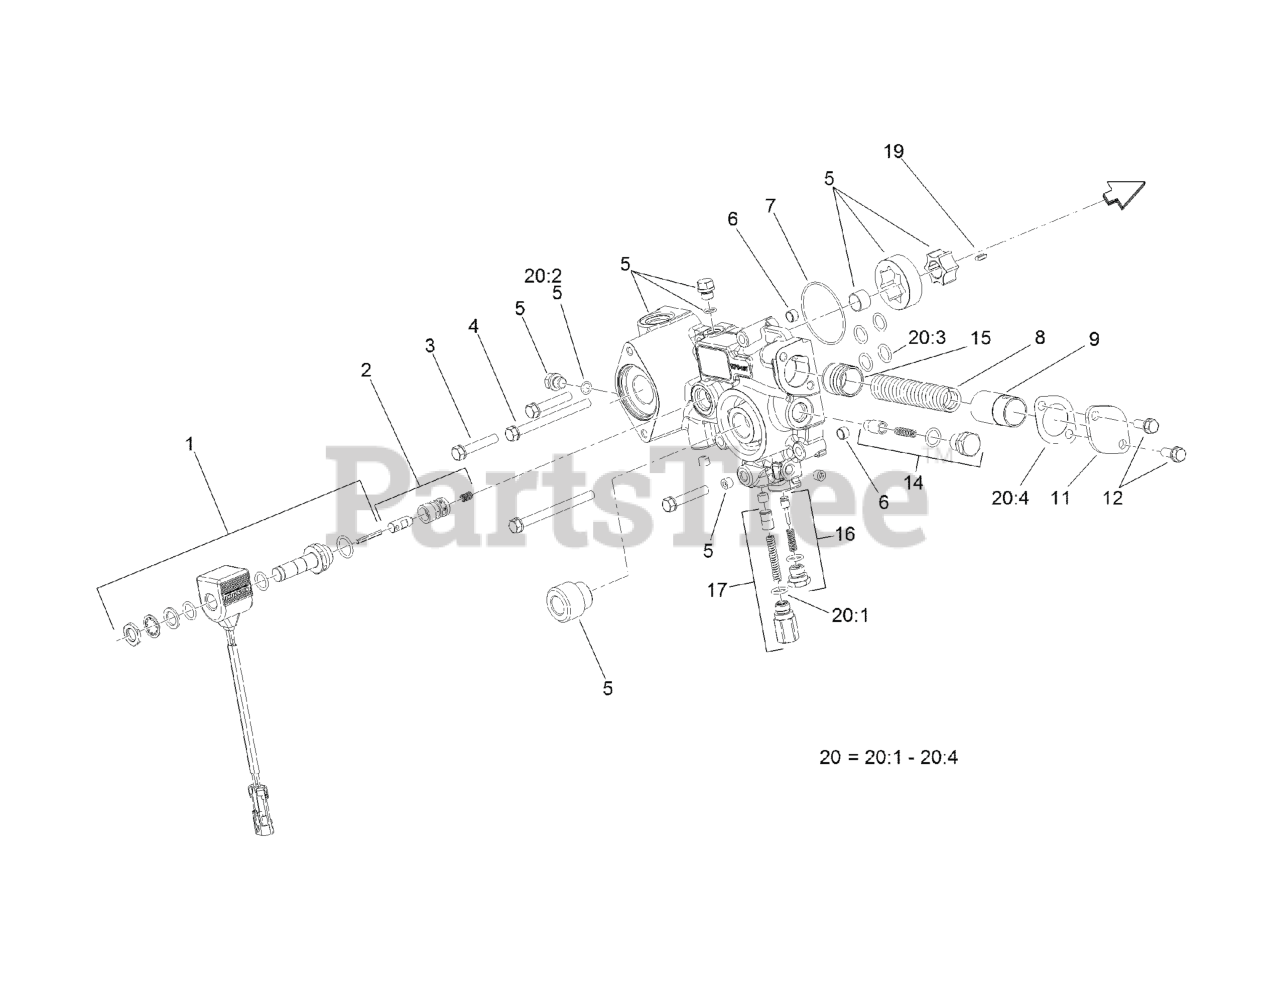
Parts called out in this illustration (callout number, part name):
1	SOLENOID ASM
2	SOLENOID VALVE ASM
5	PUMP BODY ASM
12	BOLT AND WASHER ASM
14	FILTER BYPASS VALVE ASM
16	CHARGE RELIEF VALVE ASM
17	PRESSURE VALVE ASM
20	CHARGE PUMP SEAL KIT
20:2	O RING-PLUG
20:3	Packing
